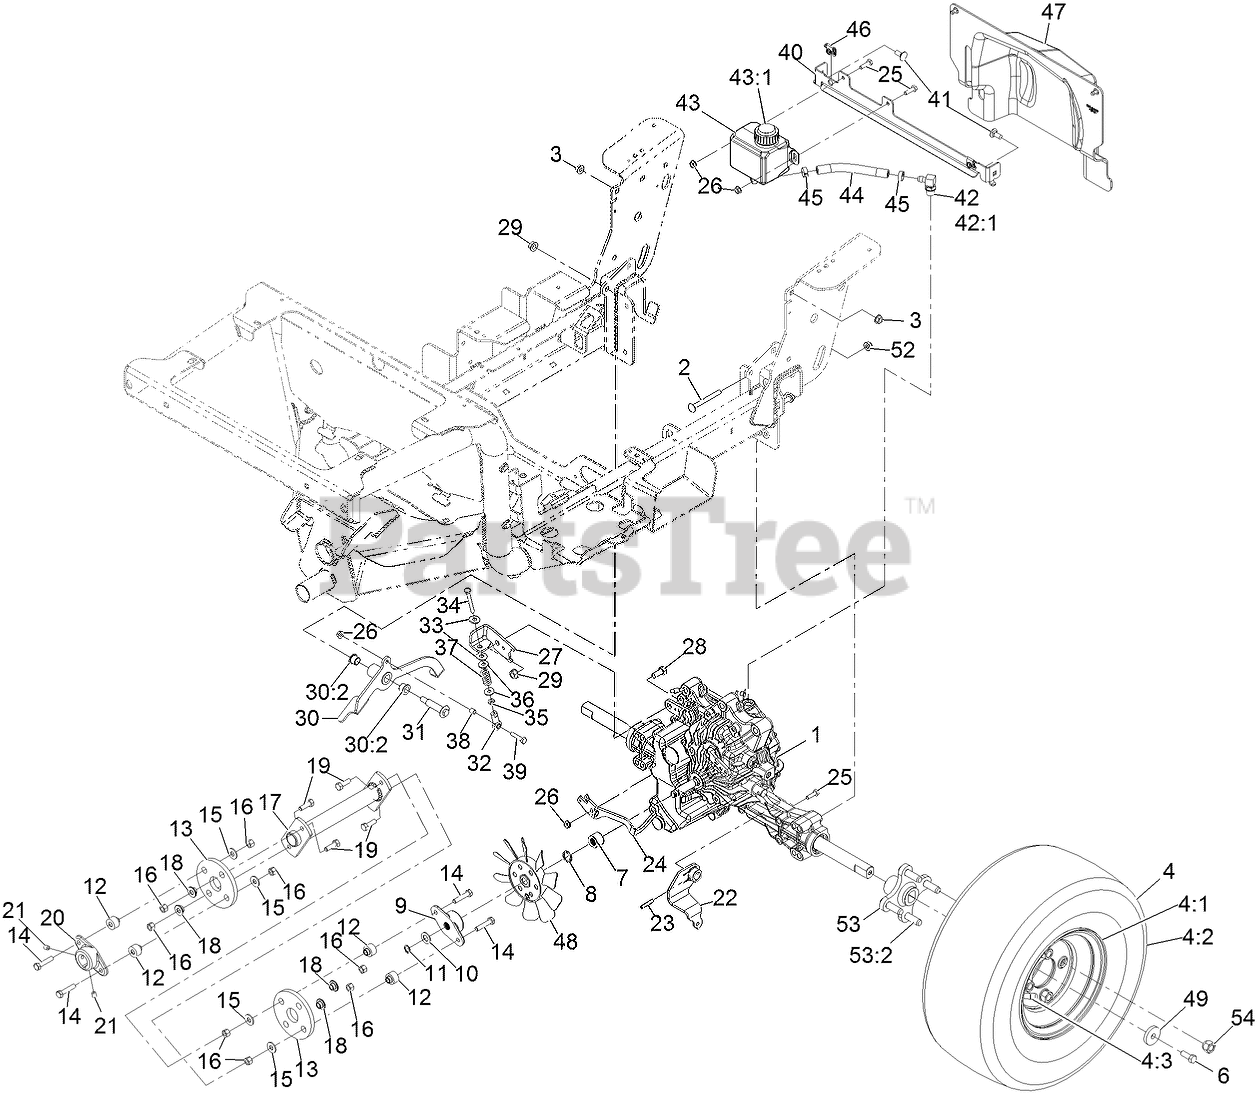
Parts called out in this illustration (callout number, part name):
1	TRANSAXLE
2	SCREW-CARR
4	Wheel And Tire ASM(18X7.5-8)
4:1	TIRE-4 PLY
4:2	Wheel, 8 X 5.375
4:3	Stem-Valve
6	SCREW-HH
7	SPACER-SHAFT, INPUT
8	WASHER-SPRING
9	HUB-SHAFT, TRANSAXLE
10	SPACER
11	RING-RETAINING
12	SPACER-COUPLING, RUBBER
13	COUPLING-RUBBER
14	SCREW-HH
15	WASHER-FLAT
16	NUT-HEX
17	Drive Shaft ASM, Welded
18	SPACER-COUPLER, RUBBER
19	SCREW-HH
20	HUB-SHAFT, ENGINE
21	SETSCREW
22	ARM-MOTION
23	PIN-SPIRAL
24	ARM-RELEASE
25	SCREW-HH
27	ARM-BRAKE
28	SCREW-HH
30	BRAKE LEVER ASM
30:2	BEARING-FLANGE
31	BOLT-SHOULDER
32	ROD END-BALL JOINT
33	WASHER-SPRING
34	SCREW-HH
35	NUT-JAM
36	WASHER-FLAT
37	SPRING-COMPRESSION
38	SPACER
39	SCREW-HH
40	BRACKET-MOUNT, TANK
41	SCREW-CARR
42	FITTING-90 DEG
42:1	O-RING
43	TANK ASM
43:1	CAP-TANK
44	HOSE-EXPANSION
46	RECEPTACLE-CLIP, MINI
47	TRANSAXLE COVER ASM
48	FAN-7 INCH
49	WASHER-CLUTCH
52	NUT-HF, NI
53	WHEEL HUB ASM
53:2	STUD-TYPE, DRIVE
54	NUT-LUG
